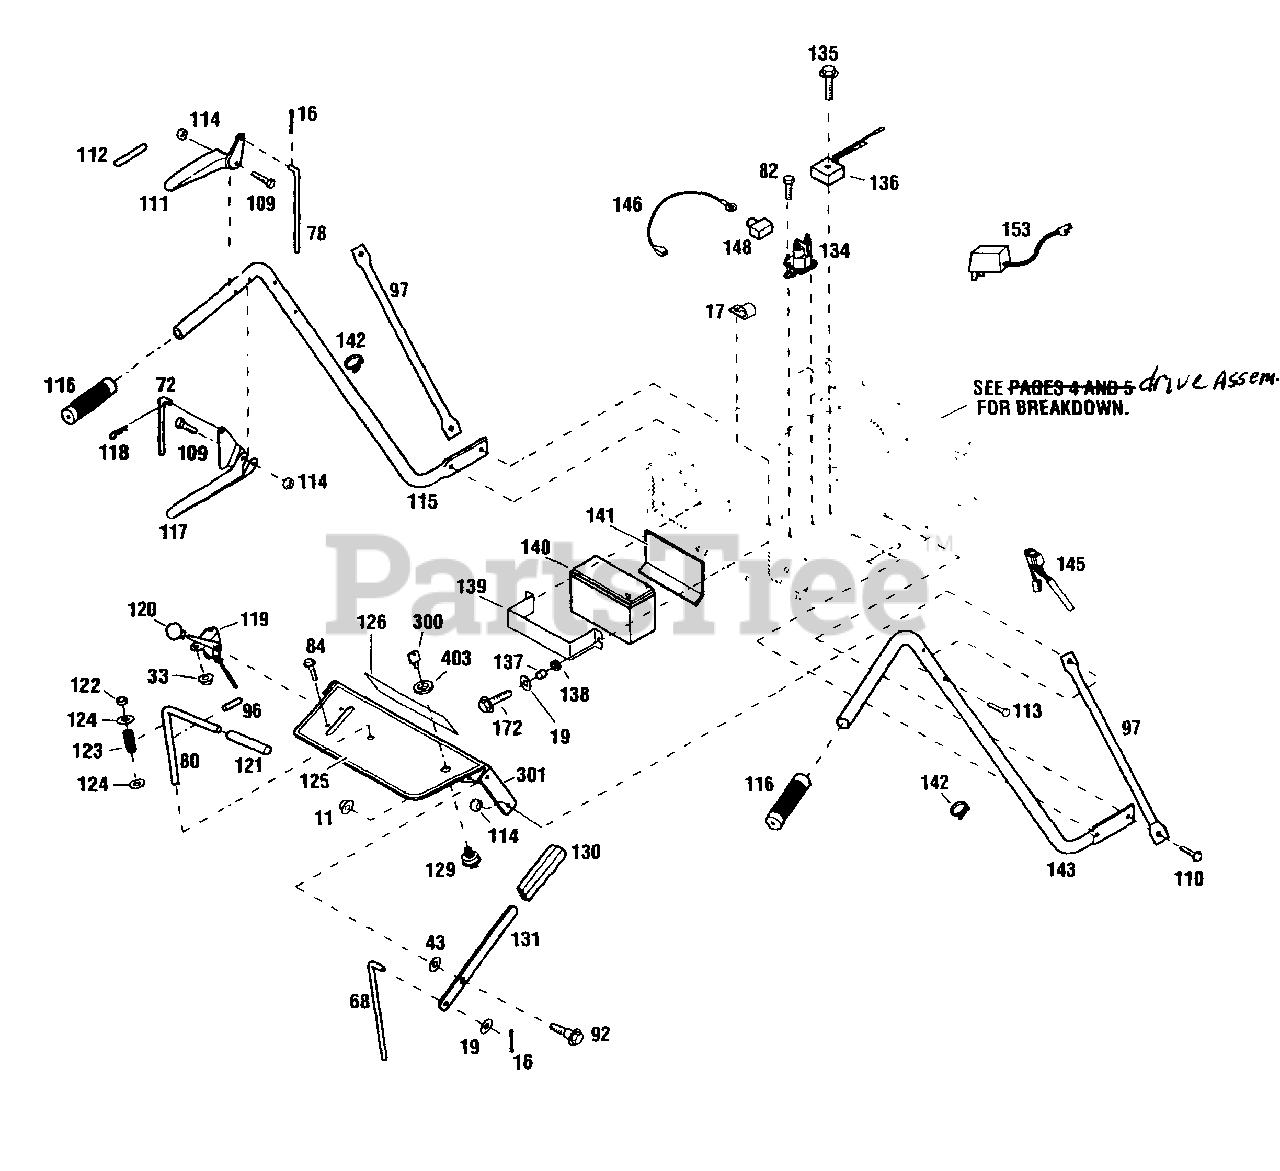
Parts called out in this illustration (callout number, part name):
11	Range Locknut, 3/8-16
16	Cotter Pin, 3/32 x 5/8
19	Flat Washer, 5/16
33	Flange Locknut, 1/4-20
43	Flat Washer, 1/2
68	Upper Blade Rod
72	Upper Transmission Rod
78	Upper Brake Rod
82	Thread Cut. Screw, 1/4-20 x 1/2
84	Flange Lock Screw, 1/4-20 x 1/2
92	Shoulder Bolt
96	Roll Pin, 1/4 x 2-1/4
97	Brace, Handlebar
109	Hex Screw, 1/4-20 x 1-3/4
110	Flange Lock Screw, 5/16 x 3/4
111	Control Handle
112	Operator Presence Control Decal
113	Hex Screw, 1/4-20 x 1-3/4, Grade 8
114	Locknut, 1/4-20
115	Left Handlebar
116	Handle Grip
117	Control Handle
118	Hair Pin, 5/64
119	Throttle Control
120	Knob
121	Handle Grip
122	Nylon Bushing
123	Compression Spring
124	Flat Washer, 1/2
125	Warning Decal
126	Logo Decal
129	Ignition Switch
130	Handle Grip
131	Mower Engage Lever
134	Solenoid
135	Thread-Cut. Screw, 1/4-20 x 1-1/2
136	Regulator
137	Spacer
138	Grommet
139	Battery Bracket
140	Battery
141	Battery Pad
142	Plastic Tie
143	Right Handlebar
145	Wiring Harness
146	Wire Lead
148	Boot
153	Battery Charger (shipped loose)
172	Screw, 5/16-18 x 3/4"
300	Ignition Key
301	Console Assembly
403	Nut, Ignition Switch
